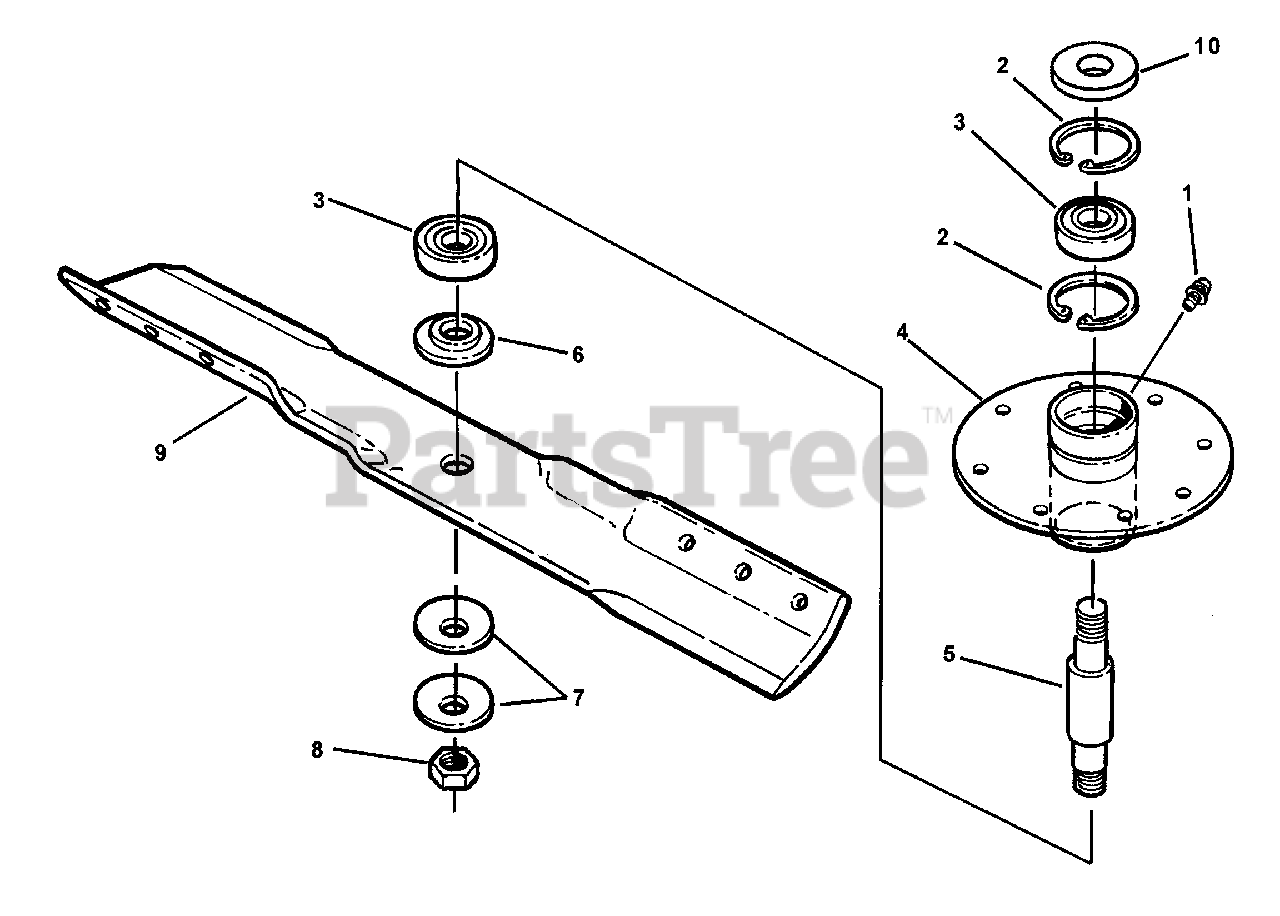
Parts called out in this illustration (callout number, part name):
1	FITTING, Lube (Press fit for .187 hole-no ball)
2	RING, Retaining
3	BEARING, Spindle
4	HOUSING, Spindle
5	SHAFT, Spindle (7.155" Long)
6	WASHER, Spindle
7	WASHER, Belleville, 19/32" I.D. x 1-3/4" O.D.
8	NUT, 9/16-18 Hex Jam
9	BLADE, 19"
10	SPACER, Pulley
